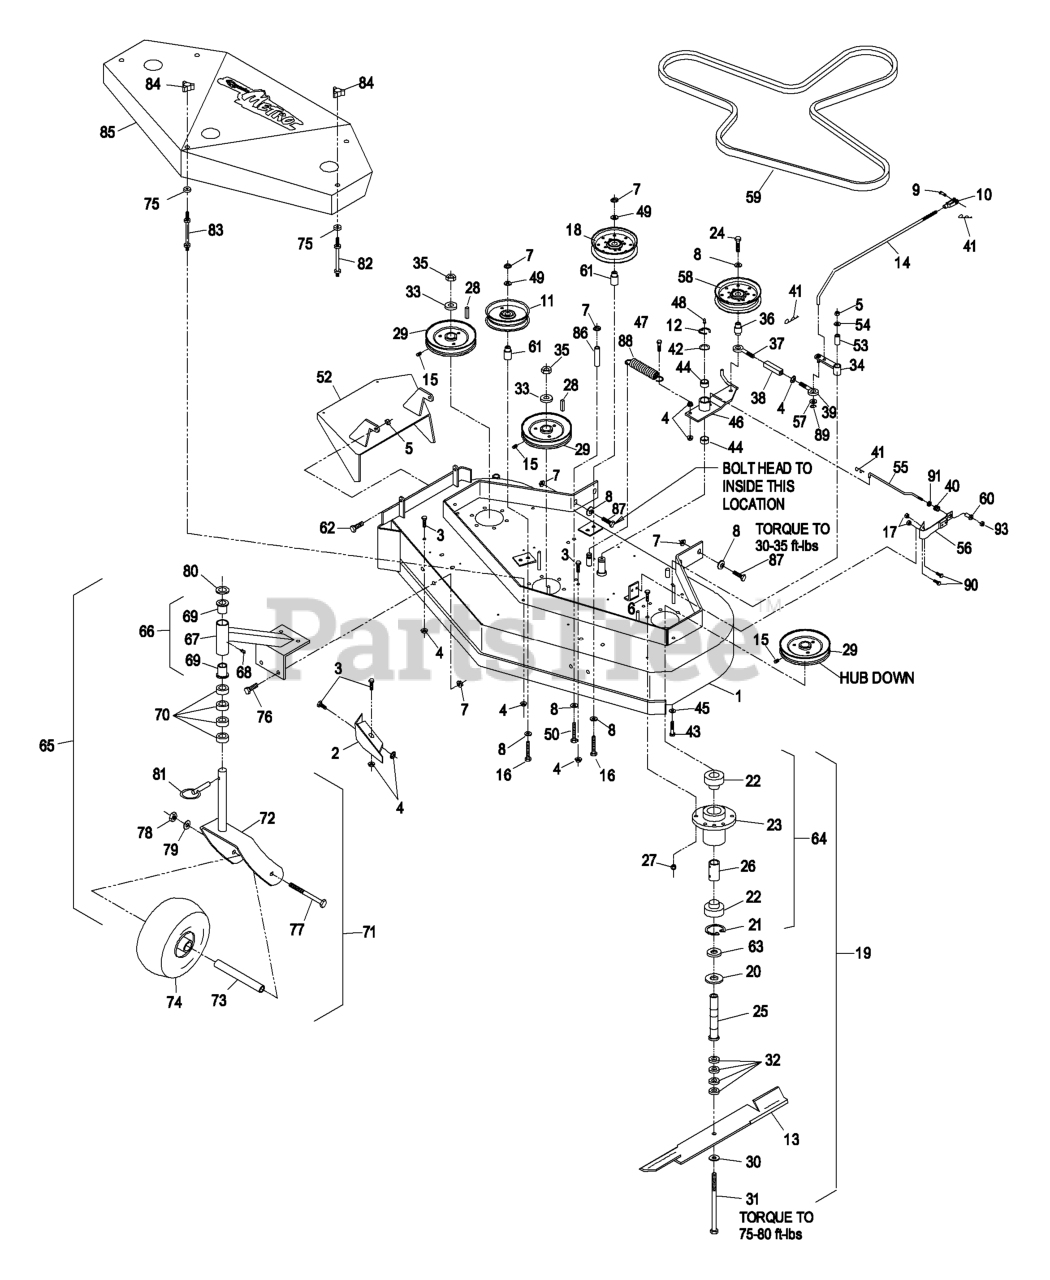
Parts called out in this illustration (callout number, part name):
1	DECK-SERVICE, 48
2	BAFFLE-DOGLEG
3	SCREW-HH
5	NUT-LOCK, NI
6	SCREW-HH
7	NUT-HHF, WHIZ
8	WASHER-BELLEVILLE
9	PIN-CLEVIS
10	YOKE-ADJUSTABLE
11	PULLEY-IDLER
12	RING-RETAINING, EXT
14	ARM-ASSIST, LINKAGE
15	SCREW-SET
16	SCREW-HH
17	NUT-LOCK, NI
19	HOUSING,CUTTER COMPLETE(S
20	GUARD-BEARING, BOTTOM
21	RING-SNAP
22	BEARING
24	SCREW-HH
25	TUBE-SPINDLE, SHORT
26	SPACER-BEARING
27	NUT-LOCK, NI
29	SHEAVE
30	WASHER-SPRING
31	SCREW-CAP, HH
33	WASHER-RETAINER, SHEAVE
34	ARM-ASSIST
35	NUT-HEX
36	BUSHING-ENGAGEMENT
37	EYEBOLT-THREAD, LH
38	BODY-TURNBUCKLE
39	EYEBOLT-THREAD, RH
40	SPRING-COMPRESSION
41	PIN-COTTER
42	WASHER-SPINDLE
43	SCREW-HH
44	SLEEVE-BEARING
45	WASHER-SPRING
46	ENGAGE ARM ASM
47	SCREW-HH
48	FITTING-GREASE
49	WASHER-FLAT
50	SCREW-HH
51	NUT-LOCK, NI
52	WLD,CHUTE 48
53	TUBE-PIVOT
54	WASHER-FLAT
55	ROD-BRAKE
56	PAD AND SPRING ASM
57	WASHER-PLAIN
59	BELT,BLADE 48
60	SPACER-FLANGED
62	SCREW-HH
63	SPACER-PULLEY/BEARING
65	CASTER/MOUNT ASM
66	SUPPORT ASM
68	Grease Zerk, 1/8 N.P.T.
69	BEARING-FLANGED
70	SPACER-CASTER
76	SCREW-HH
77	SCREW-HH
78	NUT-HH
79	WASHER-LOCK
80	WASHER-FLAT
82	STUD-SHIELD, BELT (SHORT)
83	STUD-SHIELD, BELT (LONG)
84	KNOB-3 PRONG
87	SCREW-HH
88	Spring 5sp/Dr Idler
89	RING-RETAINING, EXT
90	SCREW-HH
91	RING-PUSH ON
